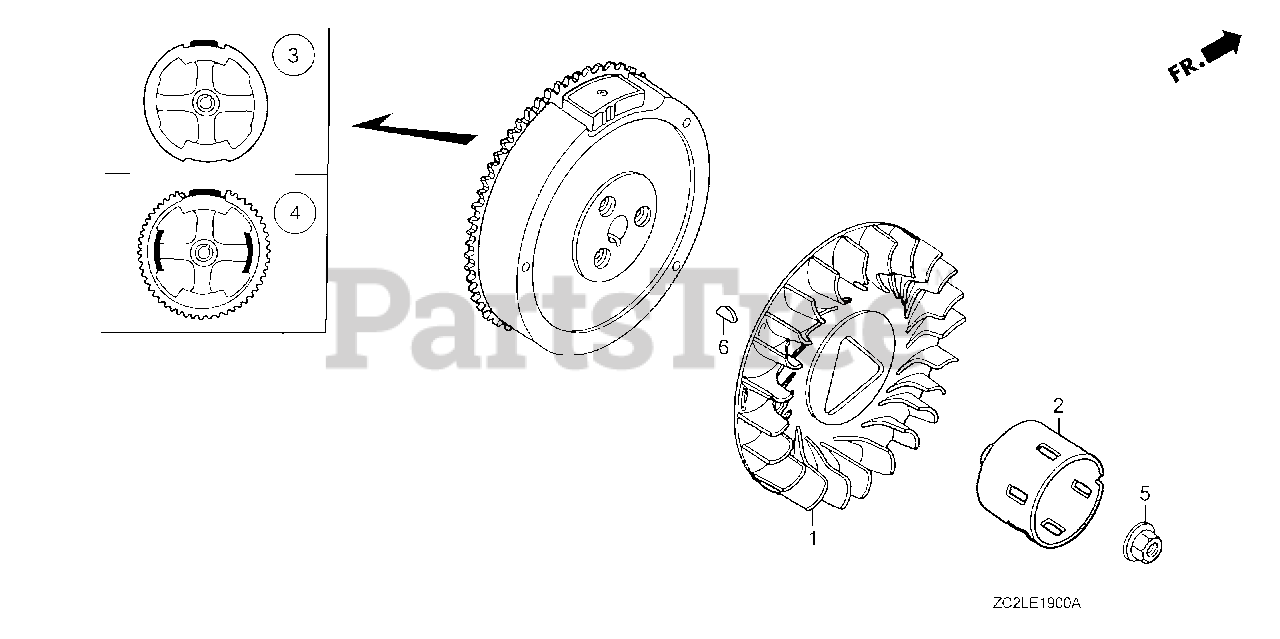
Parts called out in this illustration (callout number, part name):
1	FAN, COOLING
2	PULLEY, STARTER
4	FLYWHEEL (SEL-LAMP)
5	NUT, SPECIAL (16MM)
6	KEY, SPECIAL WOODRUFF (25X18)
